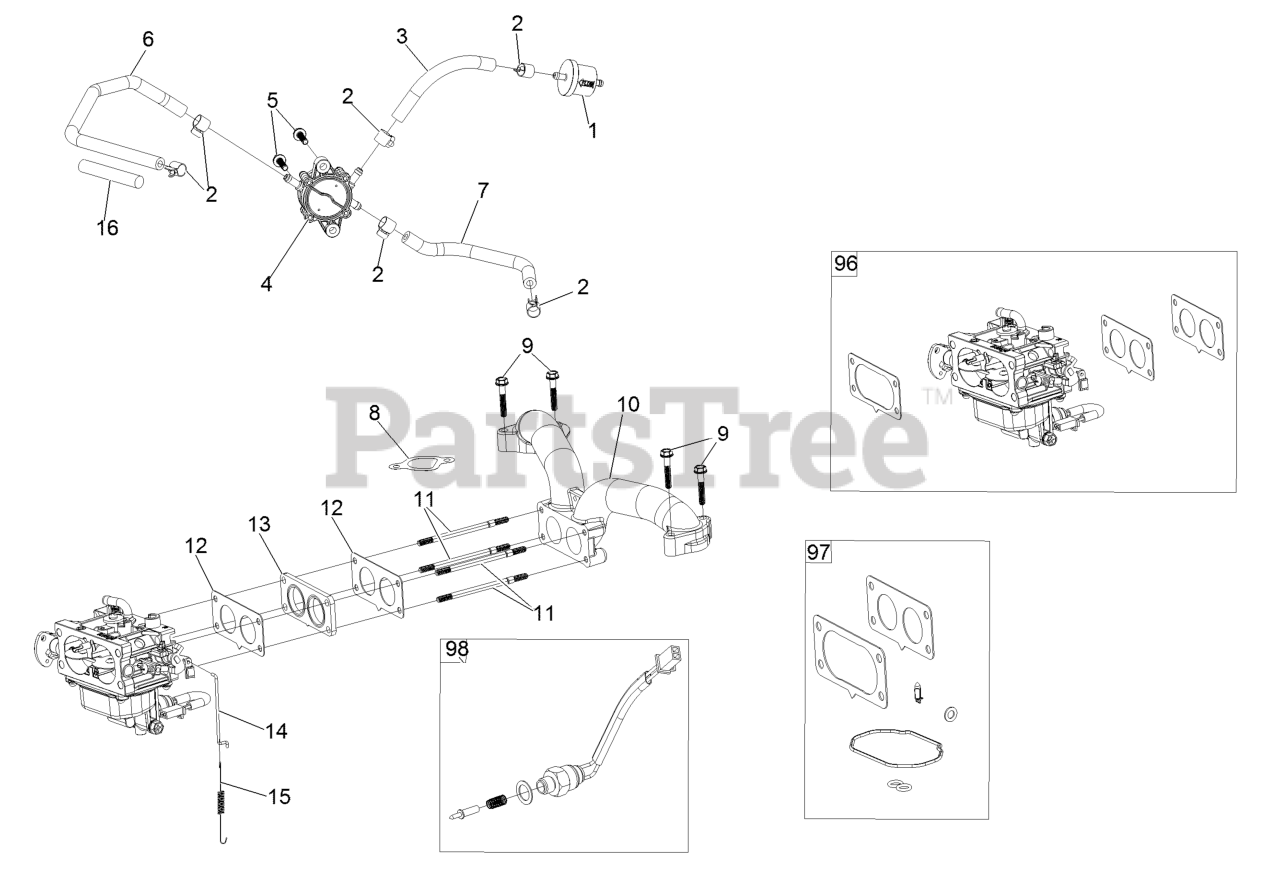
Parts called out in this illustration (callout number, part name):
1	Filter-Fuel
2	Clamp-Fuel Line
3	Line-Fuel
4	Pump-Fuel
5	Screw-HHF
6	Hose-Fuel
7	Hose-Fuel
8	Gasket-Intake
9	Screw-HHF
10	Manifold-Intake
12	Gasket-Carburetor
13	Insulator-Carburetor
14	Linkage-Throttle
15	Spring-Return, Throttle
16	Sleeve-Fuel Line Protector
96	Carburetor Replacement Kit ASM
97	Carburetor Repair Kit
98	Solenoid Kit
99	High Altitude Kit
